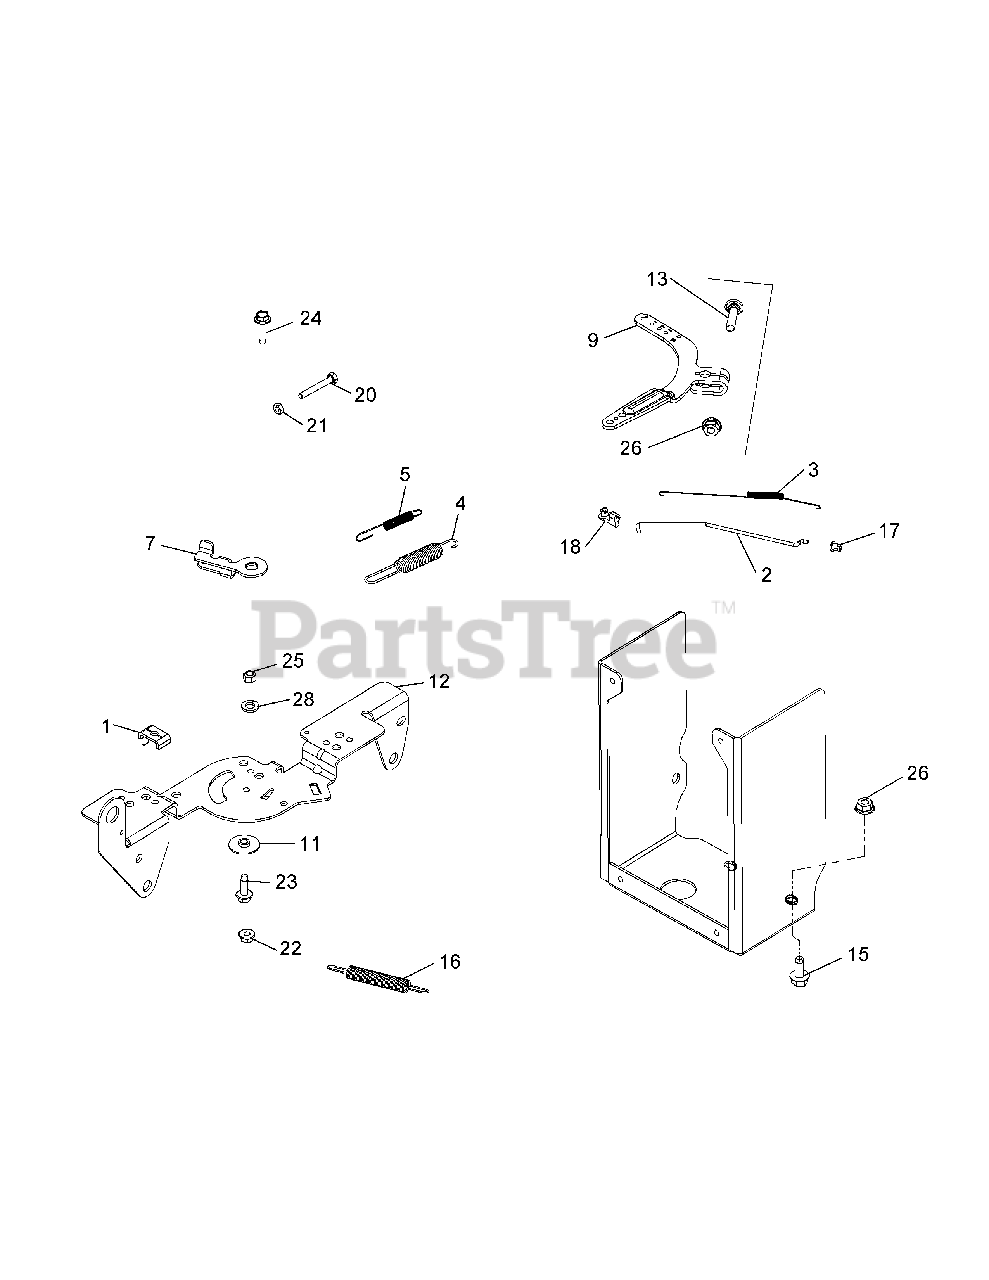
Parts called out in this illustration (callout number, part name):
1	Clamp, Cable
2	Linkage, Throttle
3	Spring, Linkage
4	Spring, Governor
5	Spring, Throttle Limiter
7	Lever, Throttle
9	Lever, Governor
11	Spacer, Control Assy
12	Bracket, Control
13	Bolt, Rd Hd Sq Neck M6x1.0x25
15	Screw, Thread Forming
16	Return Spring
17	Bushing, Linkage Retaining
18	Bushing, Throttle Linkage
20	Screw, Cap M4x.7X30
22	Nut, Flg M5x.8
23	Screw, Thread Forming
24	Screw, Thread Forming
25	Nut, Lock M5x.8
26	Nut, Flg M6x1.0
28	Washer, Spring Lock 1/4"
